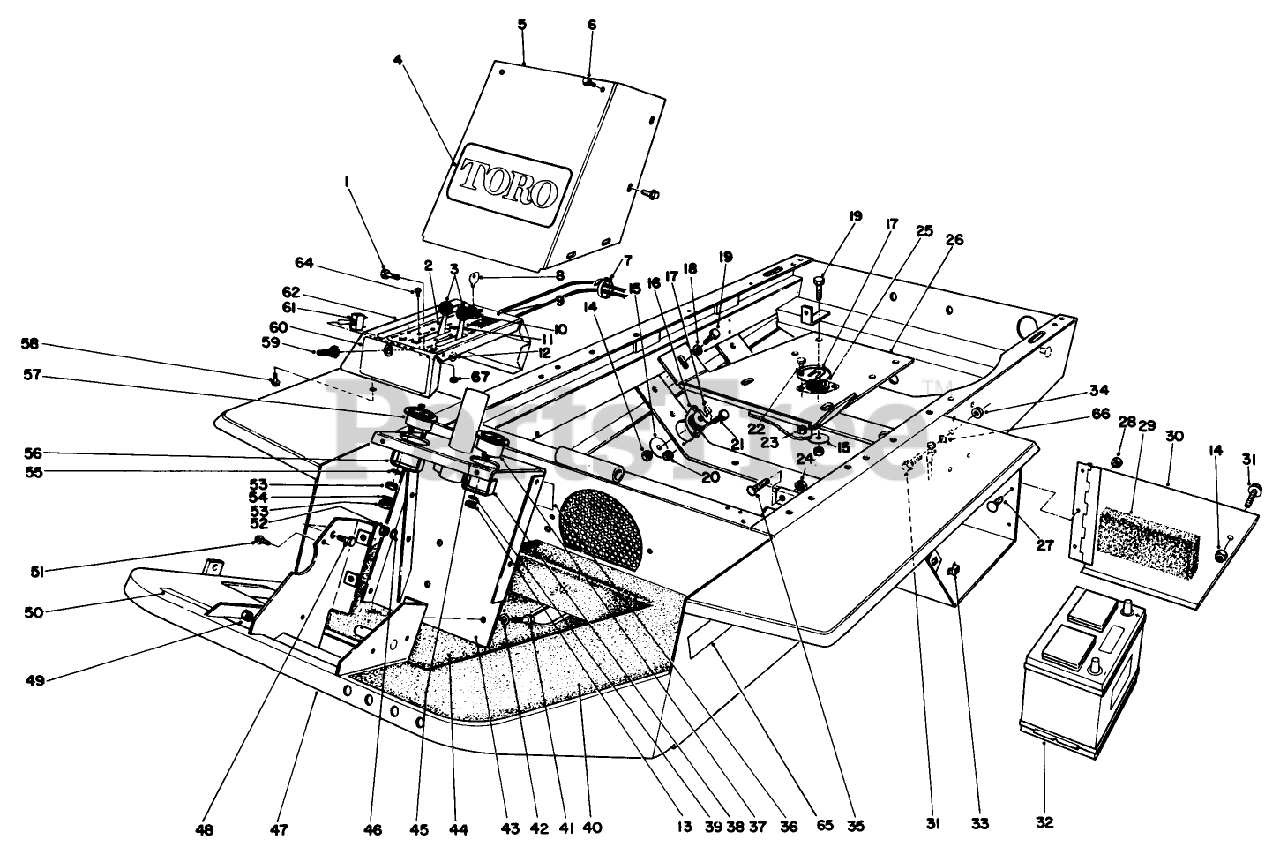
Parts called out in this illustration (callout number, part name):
1	SCREW-HHF
2	CHOKE CONTROL
4	DECAL
5	Tower Cover
6	SCREW-HHFTF
7	TIE-CABLE
8	KEY-IGNITION
9	DECAL - INST. PANEL
10	SWITCH
11	THROTTLE CONTROL
12	WASHER-FLAT
13	NUT-HEX
14	NUT-LOCK, NI
15	WASHER-REBOUND
16	ENGINE RUBBER MT
17	SHIM-AXLE
18	WASHER-FLAT
19	SCREW-HH
20	NUT-LOCK, NI
21	SCREW-HH
23	NUT-LOCK, NI
24	NUT-JAM
25	RUBBER MOUNT
26	Base-Engine
27	SCREW-HSBH
28	NUT-LOCK, NI
29	BATT BOX FOAM
30	Battery Cover
31	SCREW-HHF
32	Assembly-Battery
33	RETAINER NUT
34	NUT-HHF, WHIZ
35	SCREW-CARR
36	DECAL-OIL
37	HOUR METER
38	BRACKET F/W
39	WASHER-LOCK, INT
40	NON SKID (TUNNEL)
41	SCREW-HH
42	WASHER-LOCK
43	Steering Post
44	NON-SKID-FLOOR
45	INSTRUCTION DECAL
46	WASHER-LOCK
47	Frame Assembly
48	SCREW-HHF
49	NUT-LOCK, NI
50	DECAL-PEDAL, TRACTION
51	SCREW-HWH
52	NUT-HEX
53	NUT-HEX
54	WASHER-LOCK
55	WASHER-FLAT
56	MTG CLAMP F/W GUAGE
57	AMMETER GAUGE ASSY
58	SCREW-THD FRM,HWH
59	BOOT-SWITCH
60	BY-PASS DECAL
61	Switch-Toggle (Incl. Ref. #58)
62	Instrument Panel
64	10-24 X 5/8 PAN HD MS
65	CAUTION DECAL
66	WASHER-LOCK
67	NUT-KEPS
